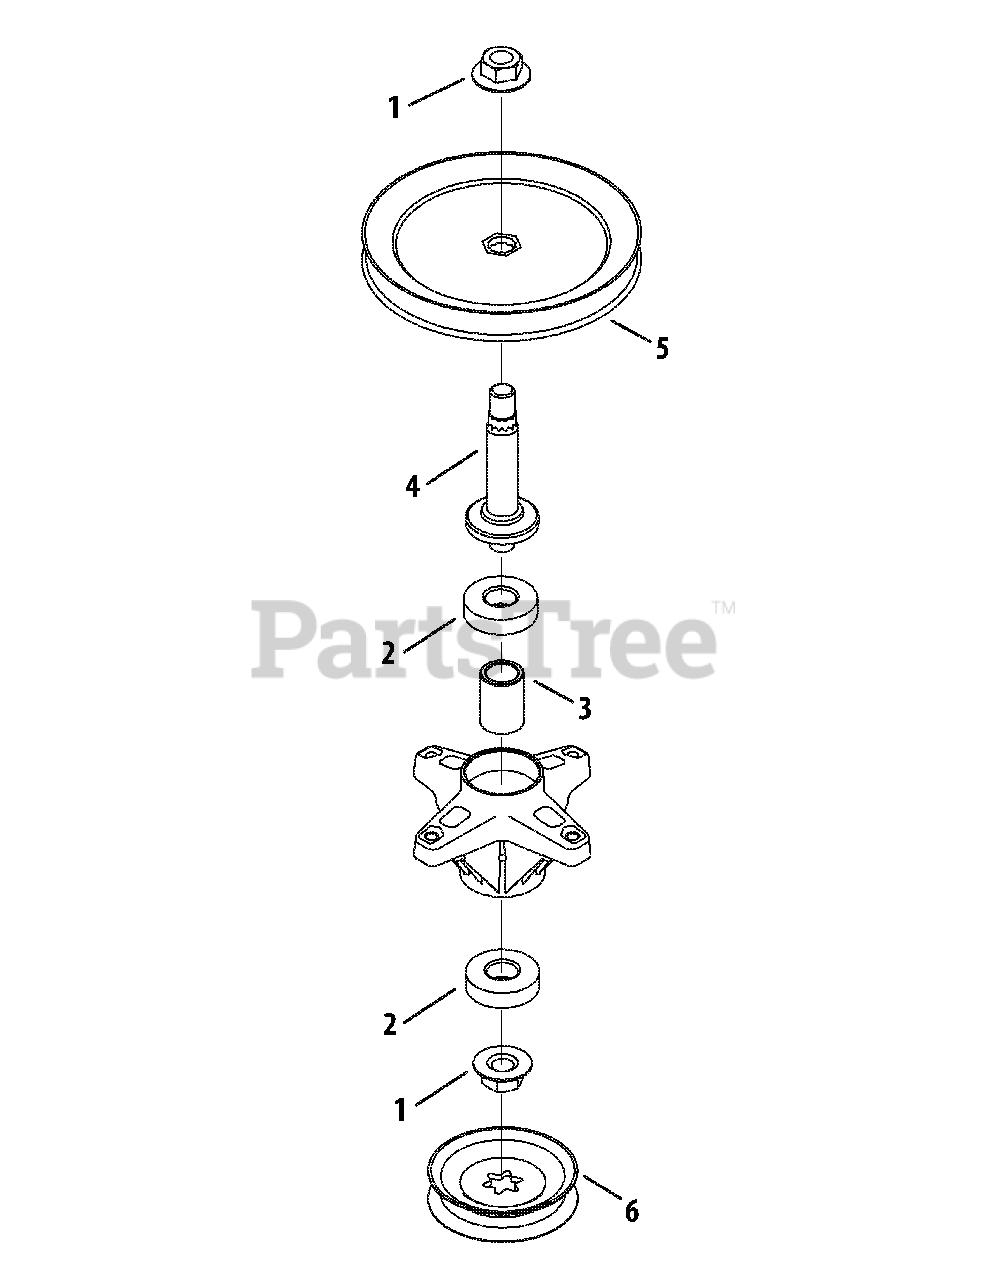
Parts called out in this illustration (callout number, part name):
1	Flange Nut 5/8-18
2	Ball Bearing
3	Spacer
4	Spindle Shaft
5	Deck Pulley 7"
6	Pulley 3.75"
